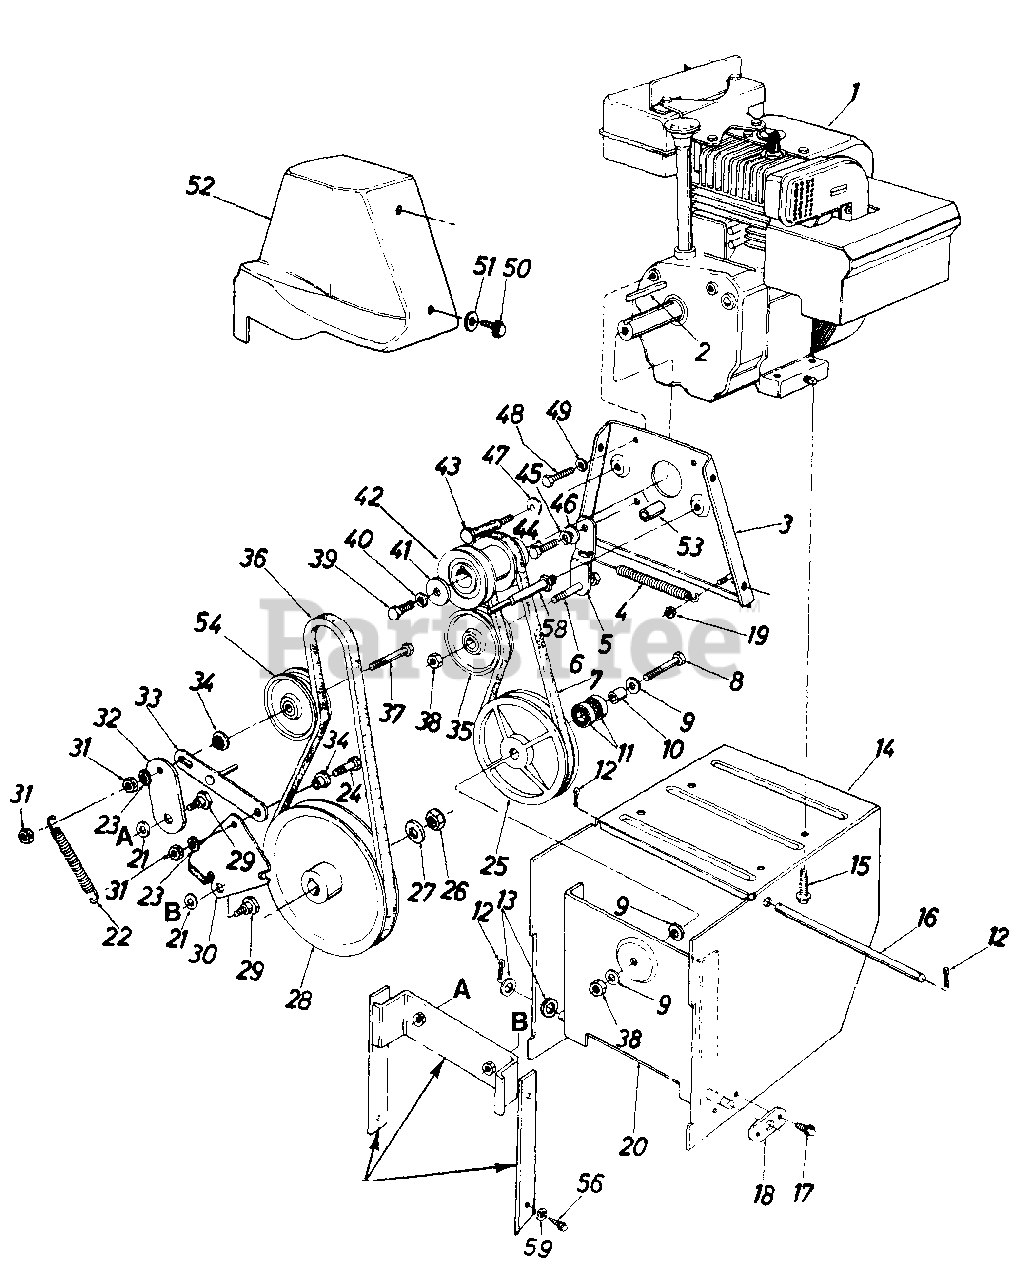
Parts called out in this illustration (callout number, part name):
1	Engine
2	Sq. Key 3/16" x 1.50" Lg. (420 & 524)
3	Engine Plate Ass'y.
4	Extension Spring .50" O.D. x 3.97" Lg.
5	Drive Clutch Idler Brkt.
6	Hex Bolt 3/8-24 x 1.25" Lg.
7	"V"-Belt
8	Hex Bolt 3/8-24 x 1.50" Lg.
9	Bell-Wash. .40" I.D. x .88" O.D. x .06
10	Spacer .38" I.D. x .62" O.D. x.75" Lg.
11	Ball Brg. .62" I.D. x 1.38" O.D. x .44
12	Cotter Pin 3/32" Dia. x .75" Lg.
13	Fl-Wash. .53" I.D. x 1.00" O.D. x .125
14	Frame Ass'y.
15	Hex Wash. Hd. Self-Tap Scr. 3/8-16 x 1.25" Lg.
16	Shaft .50" Dia. x 9.50" Lg.
17	Hex Wash. Hd. Self-Tap Scr. 1/4-20 x .50" Lg.
18	Axle Bracket
19	Hex L-Nut 1/4-20 Thd.
20	Drive Pulley Support Brkt. Ass'y.
21	Bell-Wash. .40" I.D. x 1.13" O.D.
22	Extension Spring .56" O.D. x 4" Lg.
23	L-Wash. 3/8" I.D.
24	Hex Scr. 3/8-16 x 1 25" Lg.
25	6.00" O.D. Drive Pulley Ass'y.
26	Hex Jam Cent. L-Nut 5/8-18 Thd.
27	Fl-Wash. .64" I.D. x.94" O.D. x .06
28	1/2" V-Pulley .625" I.D. x 7.50" O.D.
29	Shld. Bolt 625" Dia. x .170" Lg. (3/8-16)
30	Brake Bracket Ass'y.
31	Hex Ins. L-Nut 3/8-16 Thd.
32	Auger Clutch Idler Brkt.
33	Brake Linkage Ass'y.
34	Shld. Spacer .625" I.D.
35	Fl-Idler Pulley 2.25" O.D.
36	"V"-Belt
37	Hex Bolt 3/8-16 x 2" Lg.
38	Hex Ins. Jam L-Nut 3/8-24 Thd.
39	Hex Bolt 3/8-24 x 1.50" Lg.
40	L-Wash. 3/8" I.D.
41	Bell-Wash. .40" I.D. x 1.25" O.D.
42	Double Groove Engine Pulley
43	Shld. Scr. .498" x 3.0" Lg.
44	Hex Bolt 5/16-24 x 1.00" Lg.
45	L-Wash. 5/16" I.D.
46	Shld. Spacer .27" Lg.
47	Bell-Wash. .40" I.D. x .88" x .06
48	Hex Bolt 5/16-24 x .62" Lg.
49	L-Wash. 5/16" I.D.
50	Hex Wash. Hd. Self-Tap Scr. 1/4-20 x .50" Lg.
51	Fl-Wash. .28" I.D. x .75" O.D. x .06
52	Belt Cover
53	Spacer
54	Fl-Idler Pulley 2.75" O.D.
56	Hex Wash. Hd. Self-Tap Scr. 3/8-16 x .75" Lg.
58	Stud 3/8-16 x 3.37" Lg.
59	L-Wash. 3/8"-H.D.
